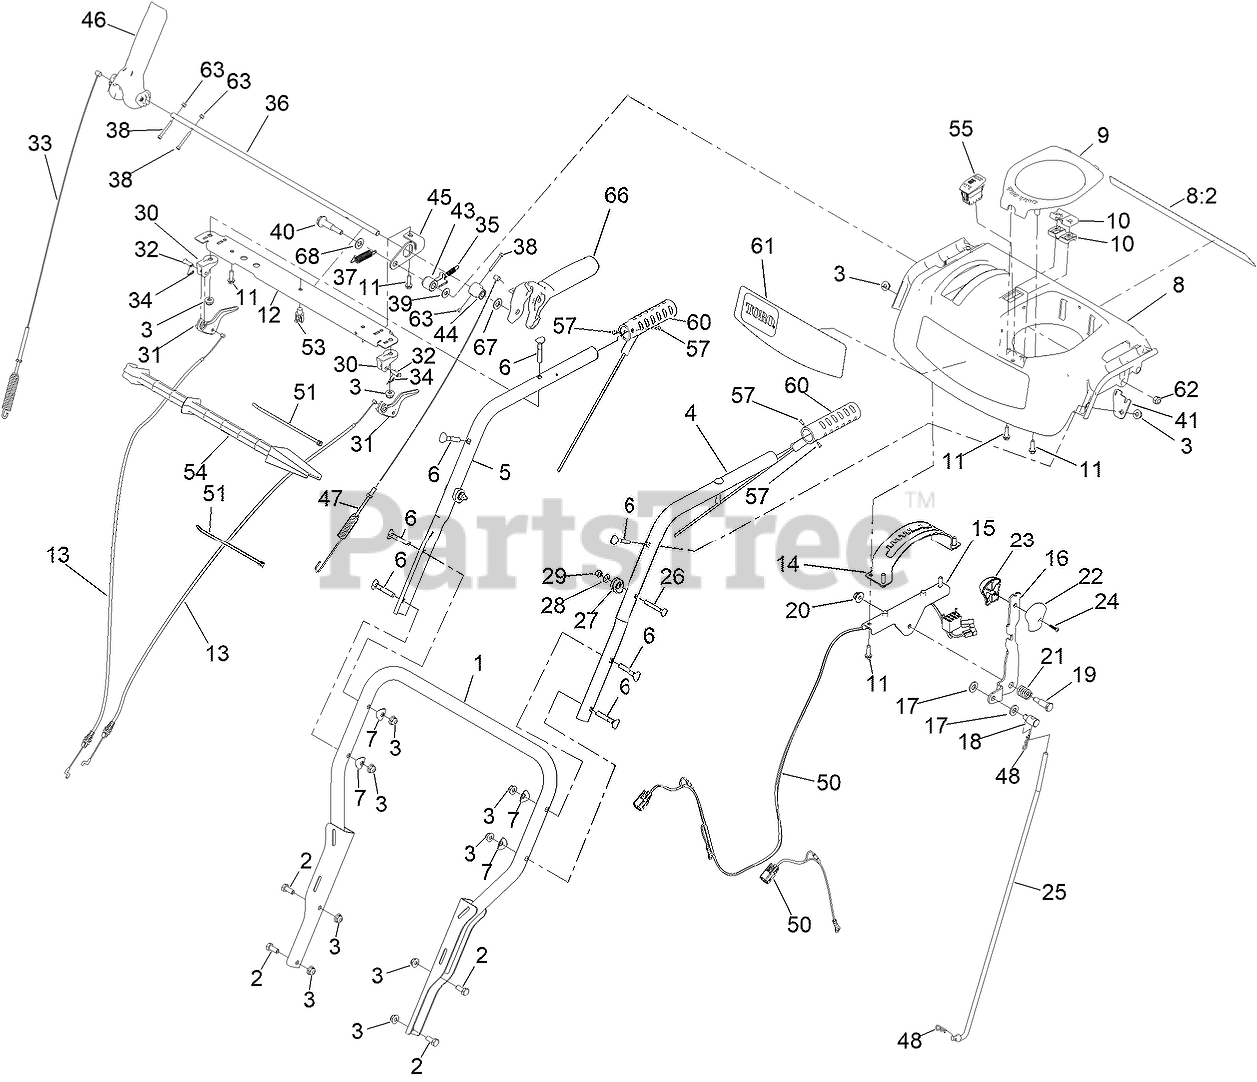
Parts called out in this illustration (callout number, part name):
1	LOWER HANDLE ASM
2	SCREW-HH
3	NUT-HF
4	HANDLE-UPPER, LH
5	HANDLE-UPPER, RH
6	SCREW-HANDLE
7	WASHER-CUP
8	PANEL-CONTROL, ASSEMBLY
8:2	DECAL-SAFETY
9	COVER-QUICKSTICK
10	SUPPORT-ROD
11	SCREW-PLASTITE, HWH
12	BRACE-CONSOLE
13	CABLE-CLUTCH
14	GATE-SHIFT
15	BRACKET-SHIFT
16	SELECTOR-SPEED
17	WASHER-FLAT
18	TRUNNION-ROD
19	SCREW-SHOULDER, HH
20	NUT-HF
21	SPRING-COMPRESSION
22	KNOB-SHIFT, LH
23	KNOB-SHIFT, RH
24	SCREW-PPH
25	ROD-SHIFT
26	BOLT-CARR
27	CLAMP-CABLE
28	WASHER-FLAT
29	NUT-HEX
30	MOUNT-LEVER, CLUTCH
31	LEVER-CLUTCH
32	PIN-CLEVIS
33	CABLE-AUGER
34	PIN-HAIR
35	SPRING-LOCKOUT, HANDLE
36	ROD-LOCKOUT
37	SPRING-RETURN, LEVER
38	SCREW-HSH,SPL
39	WASHER-FLAT
40	SCREW-SHOULDER
41	PLATE-SPRING
43	LATCH, LOCKOUT
44	CAM-LOCKOUT
45	LINK-LOCKOUT
46	LEVER-CONTROL
47	CABLE-TRACTION
48	PIN-HAIR
50	HARNESS-WIRE, LED AND HAND WARMERS
51	TIE-CABLE
53	CLIP-TIE
54	STICK-CLEANOUT
55	SWITCH-ROCKER, ON-NONE-OFF (HEATER)
57	RIVET-POP
60	RED HEATED GRIP
61	DECAL-CONSOLE
62	NUT-HEX
63	NUT-LOCK ROHS
66	LEVER-CONTROL
67	WASHER-FLAT
68	WASHER-FLAT
